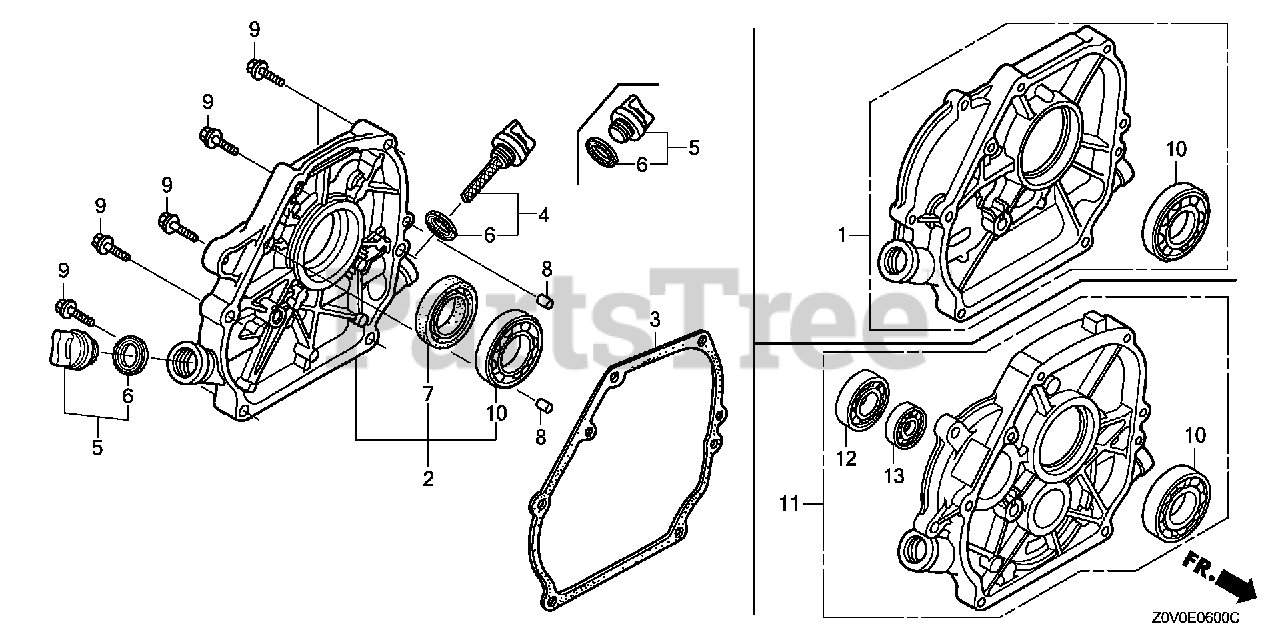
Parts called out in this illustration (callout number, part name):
2	COVER ASSY., CRANKCASE
3	GASKET, CASE COVER (NON-ASBESTOS)
4	CAP ASSY., OIL FILLER
5	CAP ASSY., OIL FILLER
6	GASKET, OIL FILLER CAP
7	OIL SEAL (25X41X6)
8	PIN A, DOWEL (8X14)
9	BOLT, FLANGE (8X32)
10	BEARING, RADIAL BALL (6205)
